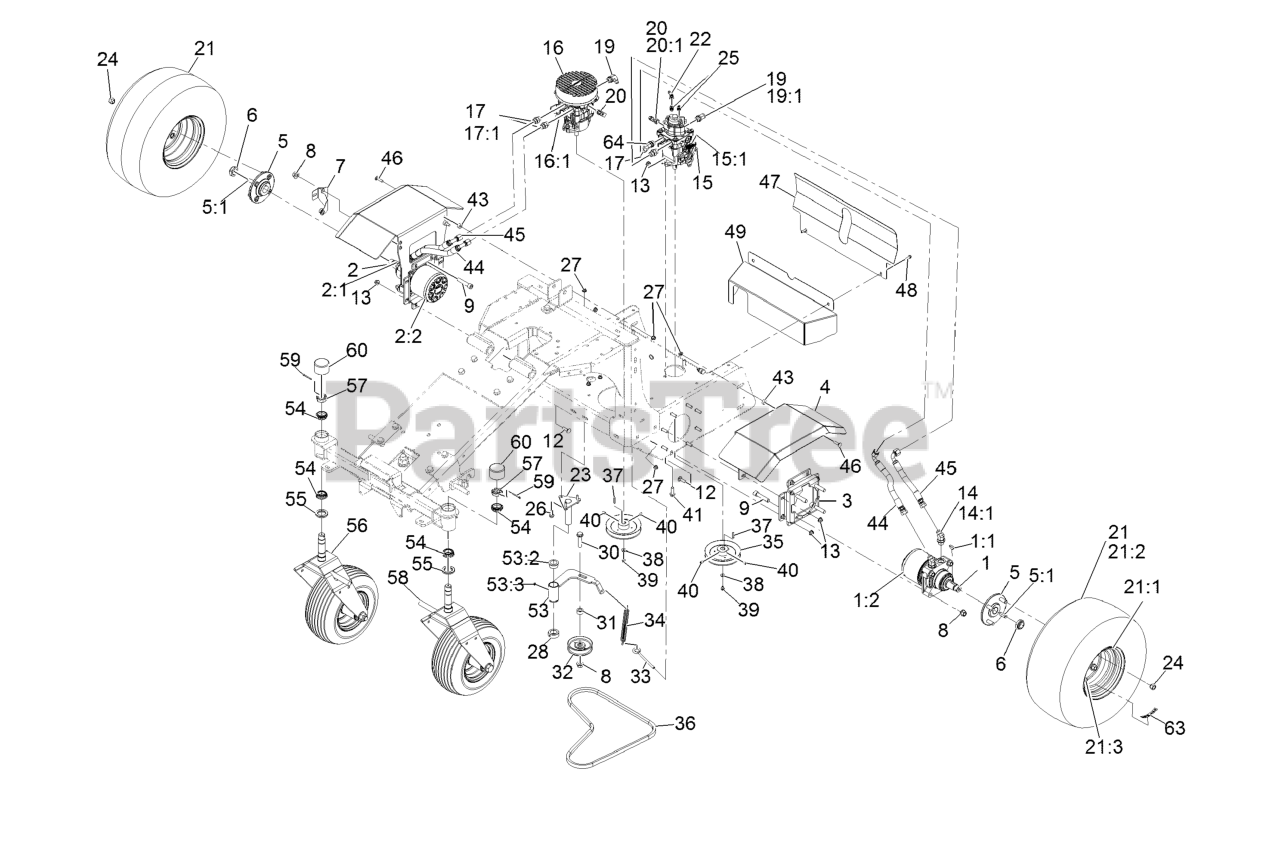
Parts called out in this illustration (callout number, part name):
1	MOTOR-WHEEL, LH
1:1	KEY-WOODRUFF
1:2	SEAL KIT
2	MOTOR-WHEEL, RH
2:1	KEY-WOODRUFF
2:2	SEAL KIT
3	X-REF 142-0270-05
4	FENDER-AE
5	HUB-WHEEL
5:1	STUD-1/2-20 X 1.55
6	LOCKNUT
7	BRACKET-HOPPER, SPEEDOMET
8	Nut-Lock 1/2-13
9	Screw-HSH
12	BOLT-CARR
13	NUT-HF, NI
14	FITTING-ELBOW, 45 DEG
14:1	O-RING
15	PUMP-HYD,LH,W/ AUX,ZPLUG,
15:1	SPRING-EXTENSION
16	PUMP-HYD, RH,W/ FAN ZPLUG
16:1	SPRING-EXTENSION
17	FITTING-STRAIGHT
17:1	O-RING
19	FITTING-ELBOW, 90 DEG
20	FITTING-ELBOW, 90 DEG
20:1	O-RING
21	WHEEL AND TIRE ASM
21:1	Rim-8 X 7, Black
21:3	Stem-Valve
22	4MJIC-4FJIC 90 DEG SWIVEL
23	PIVOT-IDLER
24	NUT-LUG
25	FITTING-STRAIGHT
26	SCREW-HH
27	NUT-HF, NI
30	Screw-HHF
32	PULLEY-IDLER, FLAT
33	5/16-18 X 6 EYE BOLT W/ 5
34	SPRING-EXTENSION
35	PULLEY, DRIVE, 5-5/8" 17M
36	B54 BELT 2011+ ZPLUG (16C
39	SCREW-HHF
40	Setscrew-HSH
41	SCREW-HHF
44	Hose ASM-HYD HP
45	Hose ASM-HYD HP
46	Bolt-Carriage 5/16-18 X 1 1/4
47	GUARD-PUMP
48	SCREW-HHF
53	ARM-IDLER, ASM
53:2	BUSHING-FLANGE
53:3	FITTING-GREASE, ZERK
54	CONE-BEARING, OUTER
55	SEAL-GREASE
56	Caster ASM - RH
57	NUT-SHH
58	Caster ASM - LH
59	Pin-Cotter
60	CAP-DUST, RUBBER
63	DECAL-TORQUE, WHEEL HUB LUG
64	FITTING-ELB 90
